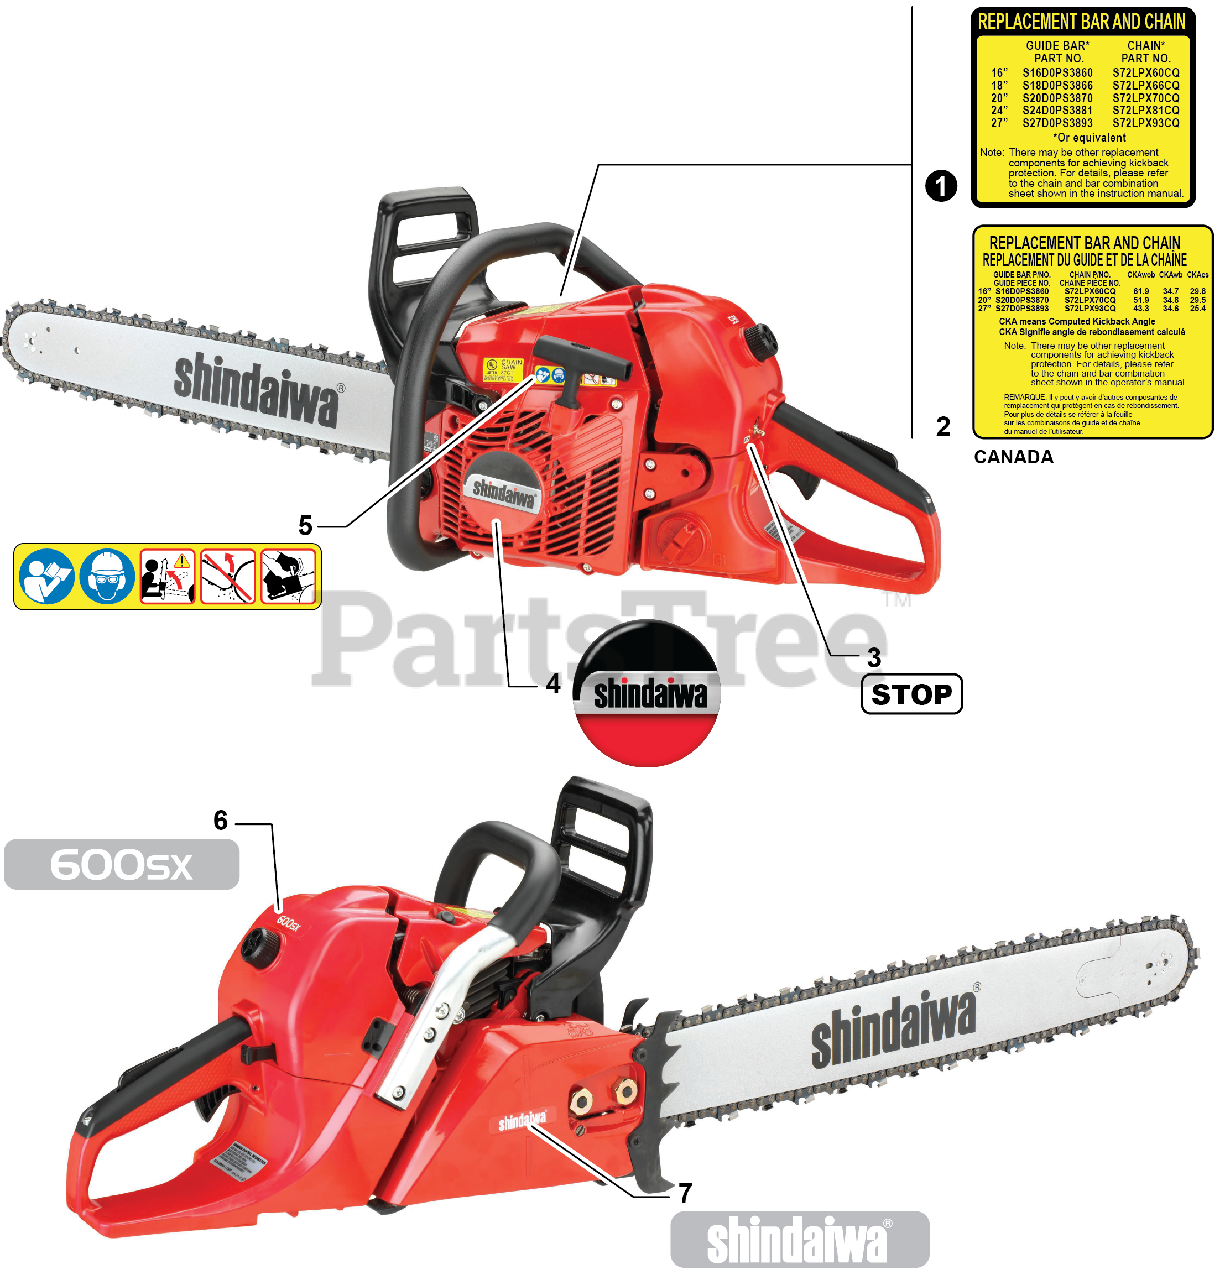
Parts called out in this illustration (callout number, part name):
1	LABEL, BAR & CHAIN
2	LABEL, BAR & CHAIN
3	LABEL, STOP
4	LABEL, STARTER - shindaiwa
5	LABEL, CAUTION
6	LABEL - MODEL 600sx
7	LABEL - shindaiwa
